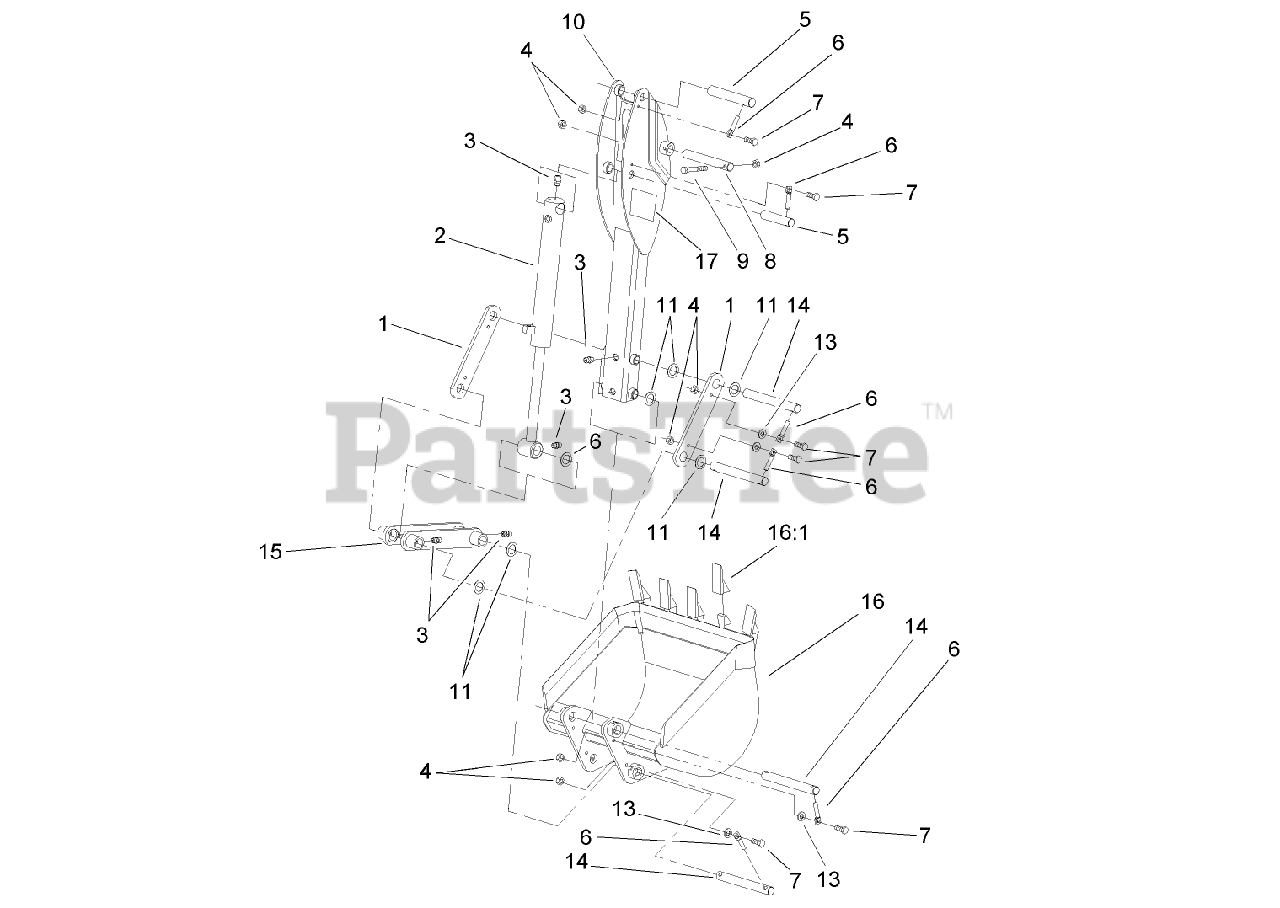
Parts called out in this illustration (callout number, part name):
1	LINK-GUIDE, BUCKET
2	HYDRAULIC CYLINDER ASM
3	FITTING-GREASE
4	NUT-LOCK
5	PIN-PIVOT
6	PIN-RETAINER, SMALL
7	SCREW-HH
8	PIN-PIVOT
9	SCREW-HH
10	DIPPERSTICK ASM
11	WASHER-FLAT
13	WASHER-PLAIN
14	PIN ASM
15	BUCKET LINK ASM
16	13 INCH BACKHOE BUCKET ASM
16:1	TOOTH-BUCKET
17	DECAL
